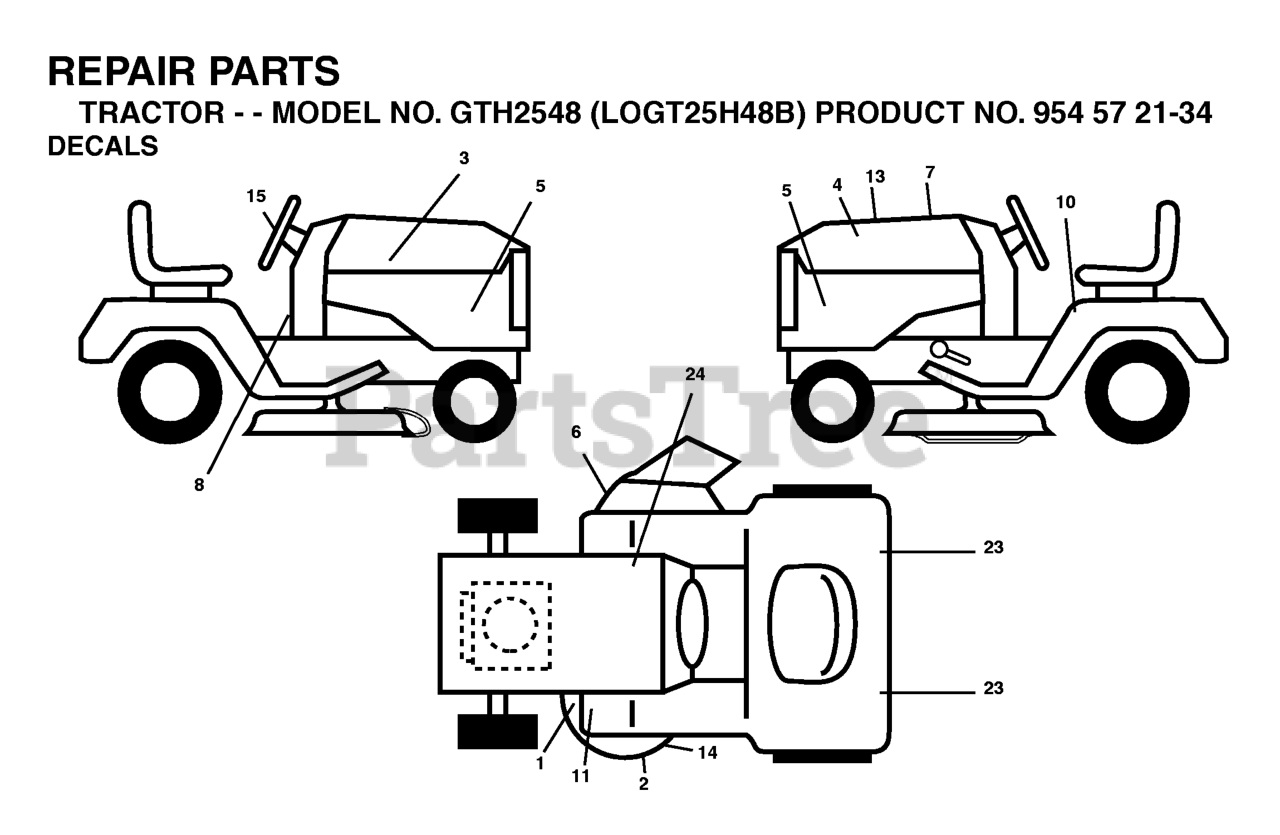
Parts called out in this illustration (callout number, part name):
1	DECAL CLUTCH/BRAKE
6	DECAL.WARN.KEEP.HAND.AWAY
7	DECAL HOOD CUST. RESP.
10	DECAL FENDER DANGER
11	DECAL, FOOTREST
14	DECAL V-BELT SCHEMATIC
15	DECAL.STEERING.HUSQ.BLUE
23	REFLECTOR-TAIL YT
24	DECAL BTRY SYMBOLS
